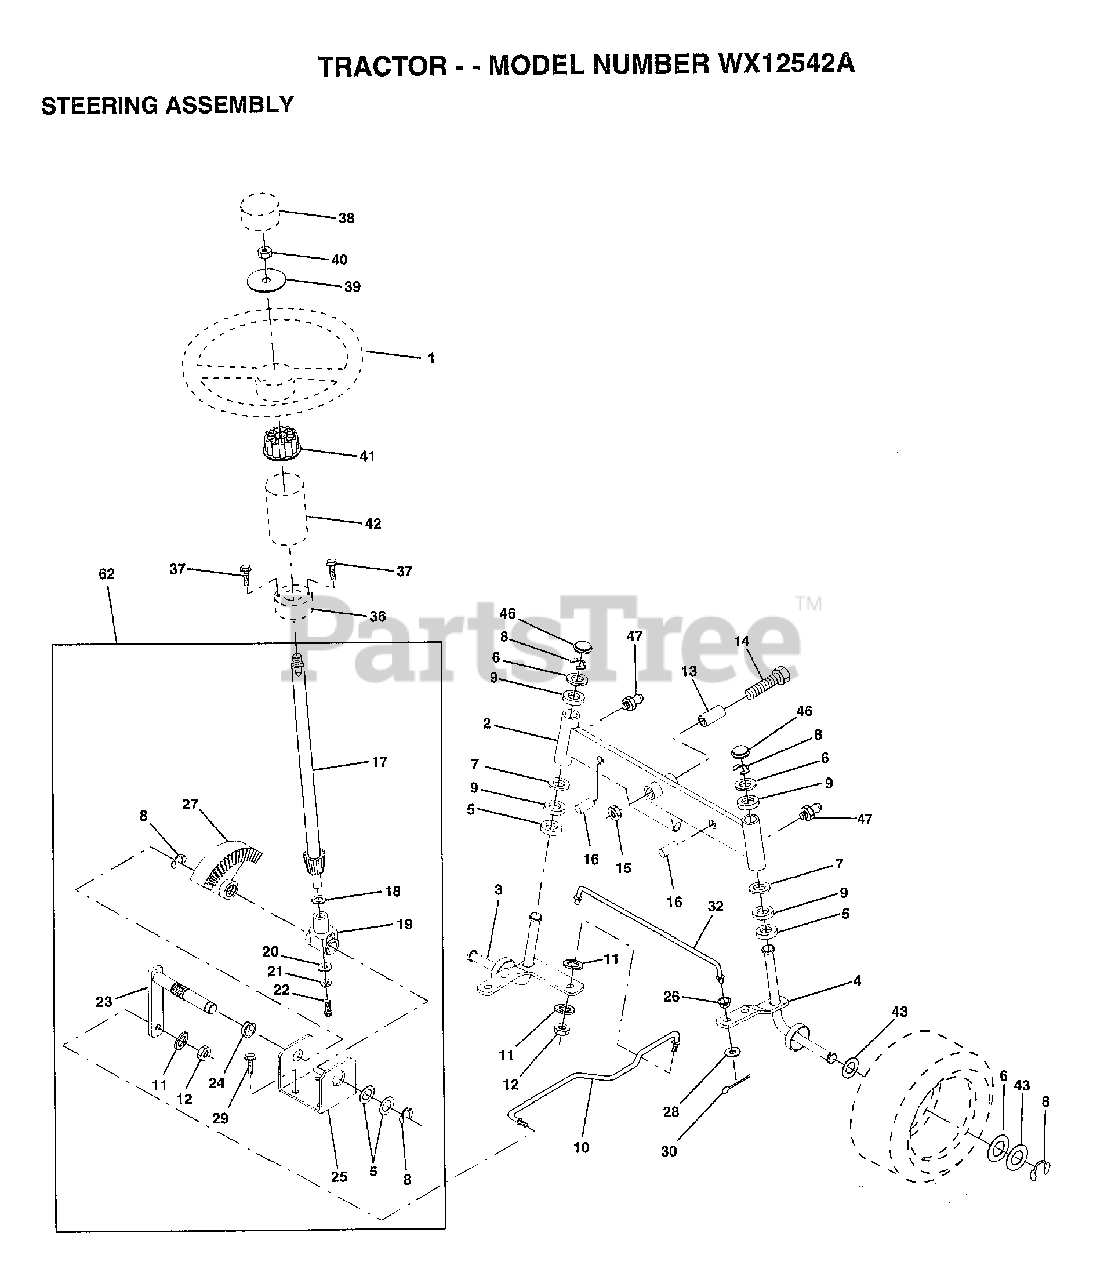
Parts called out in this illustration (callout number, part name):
2	AXLE ASM FRONT
3	SPINDLE LH
4	SPINDLE RH
5	WASHER .T
6	WASHER
7	WASHER
8	RING
9	COL. SRTG. BEAR.
11	LOCKWASHER
13	BEARING
14	BOLT HEX 5/8-11
15	"NUT-LOC,FLANGE LT"
16	AXLE PIN
17	SHAFT ASM
18	THRUST WASHER
19	SUPPORT.SHAFT
21	LOCKWASHER
22	"SCREW,SPECIAL"
24	NYLINER T
25	"BRKT,STEERING"
26	BUSHING.DRAGLINK
27	GEAR SECTOR
28	WASHER
29	SCREW
30	COTTER PIN
32	TIE ROD
38	ST WHL INSERT CAP
39	WASHER T
40	GRIPCO NUT
41	ADAPTER-WHEEL LT
42	"TUBE, STR SHAFT"
43	WASHER
46	CAP
47	ZERK M
